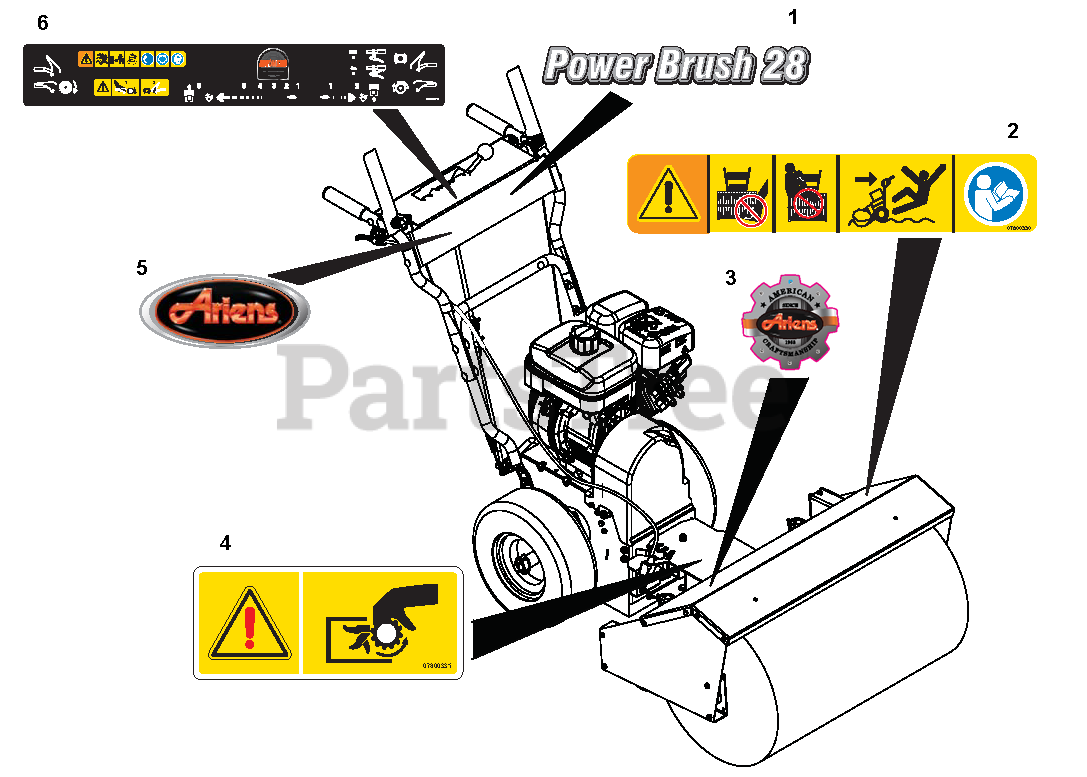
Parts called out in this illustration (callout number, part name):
1	DECAL,PWR-BRUSH
2	DECAL, DANGER -POWER BRUSH-CE
3	Decal, Ariens Heritage
4	DECAL, PTO WARNING
5	DECAL, ARIENS JEWEL
6	DECAL, CONTROL-POWER BRUSH-CE
